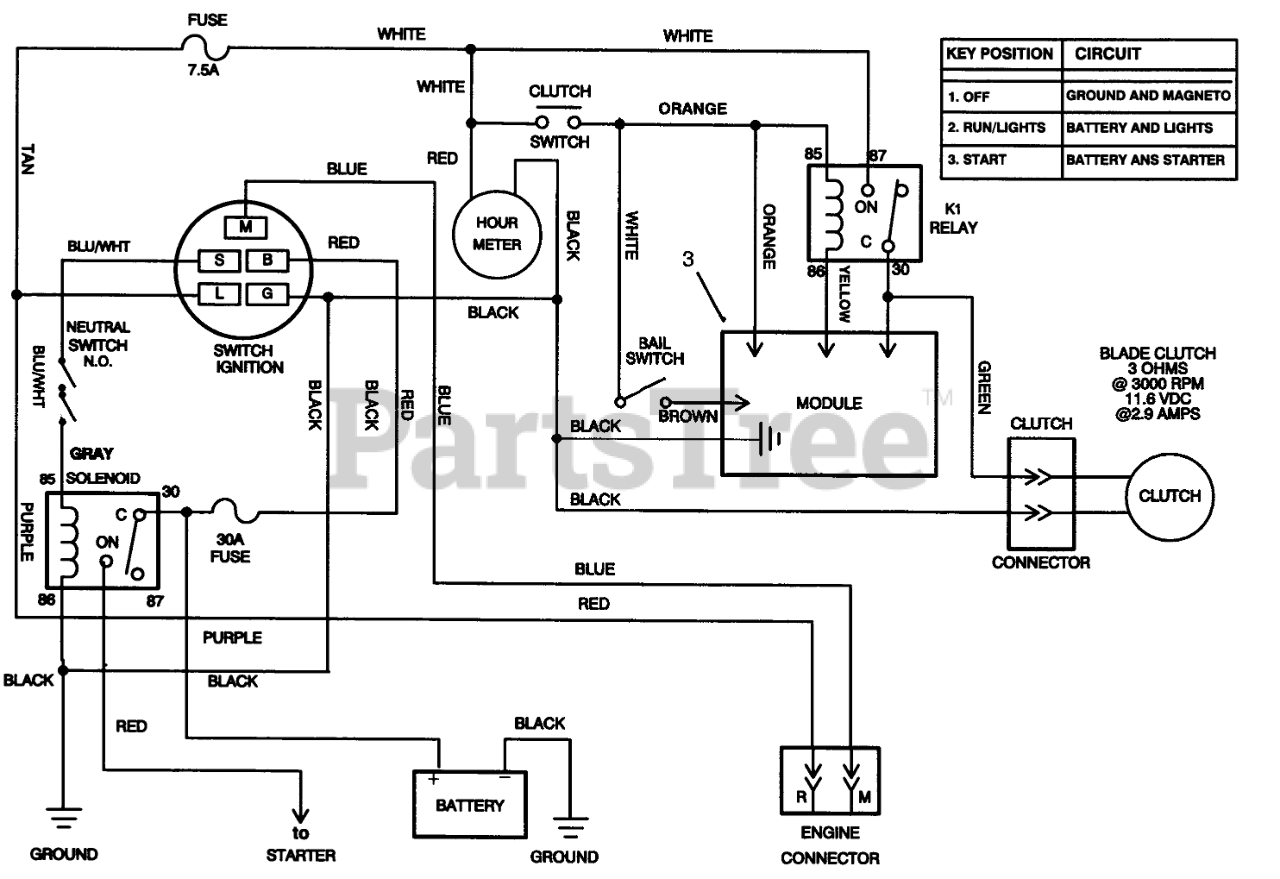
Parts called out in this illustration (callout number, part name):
1	WIRE HARNESS-14HP HYDRO
2	RELAY
3	Module
